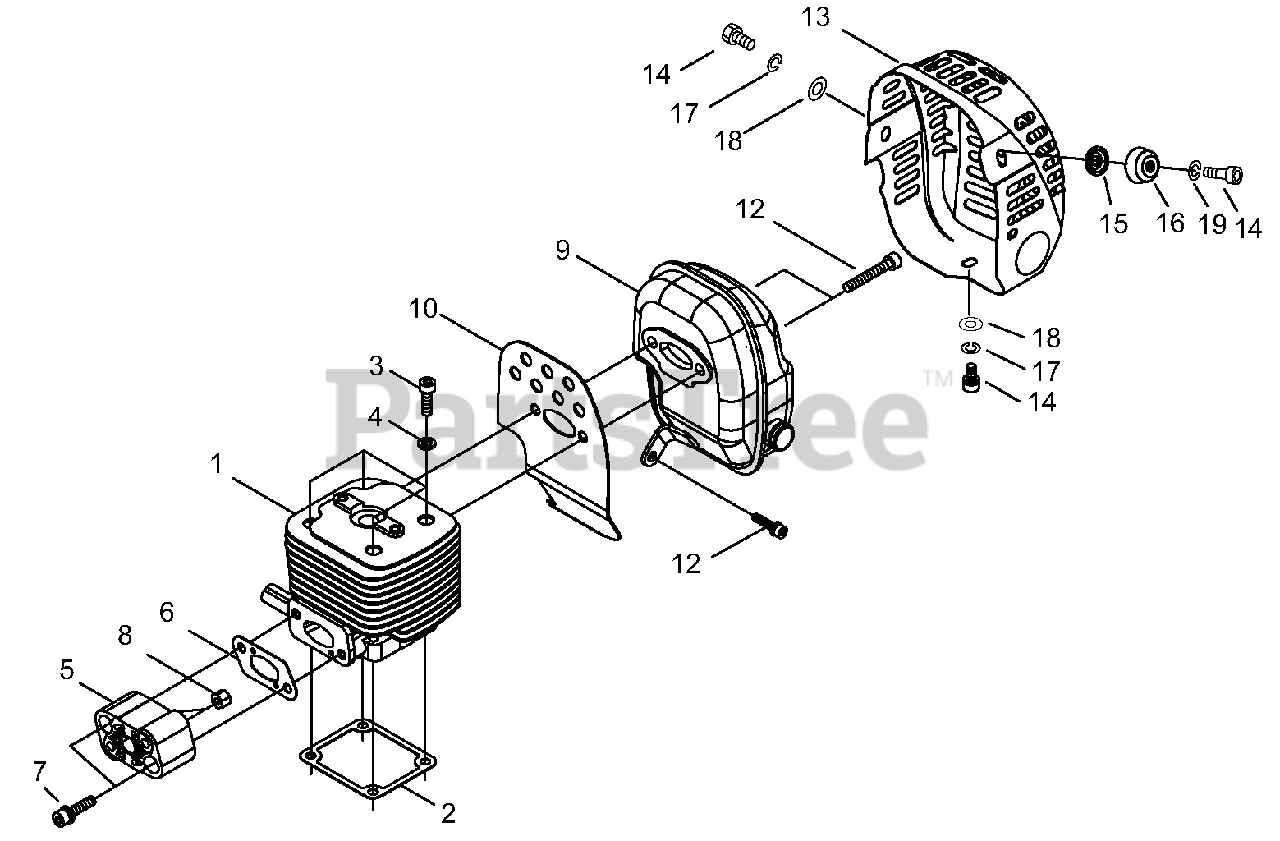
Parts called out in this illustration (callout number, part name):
1	CYLINDER
2	GASKET, CYLINDER
3	BOLT 5×25
4	WASHER, SPRING 5
5	INSULATOR
6	GASKET, INTAKE
7	BOLT M5×25
8	NUT
9	MUFFLER
10	HEAT SHIELD, EXHAUST
11	BOLT 6×25
12	BOLT M5×12
13	COVER, MUFFLER
14	BOLT 5×10
15	WASHER
16	COVER
17	WASHER, SPRING 5
18	WASHER 5.5×12×0.8
19	WASHER, SPRING 5
